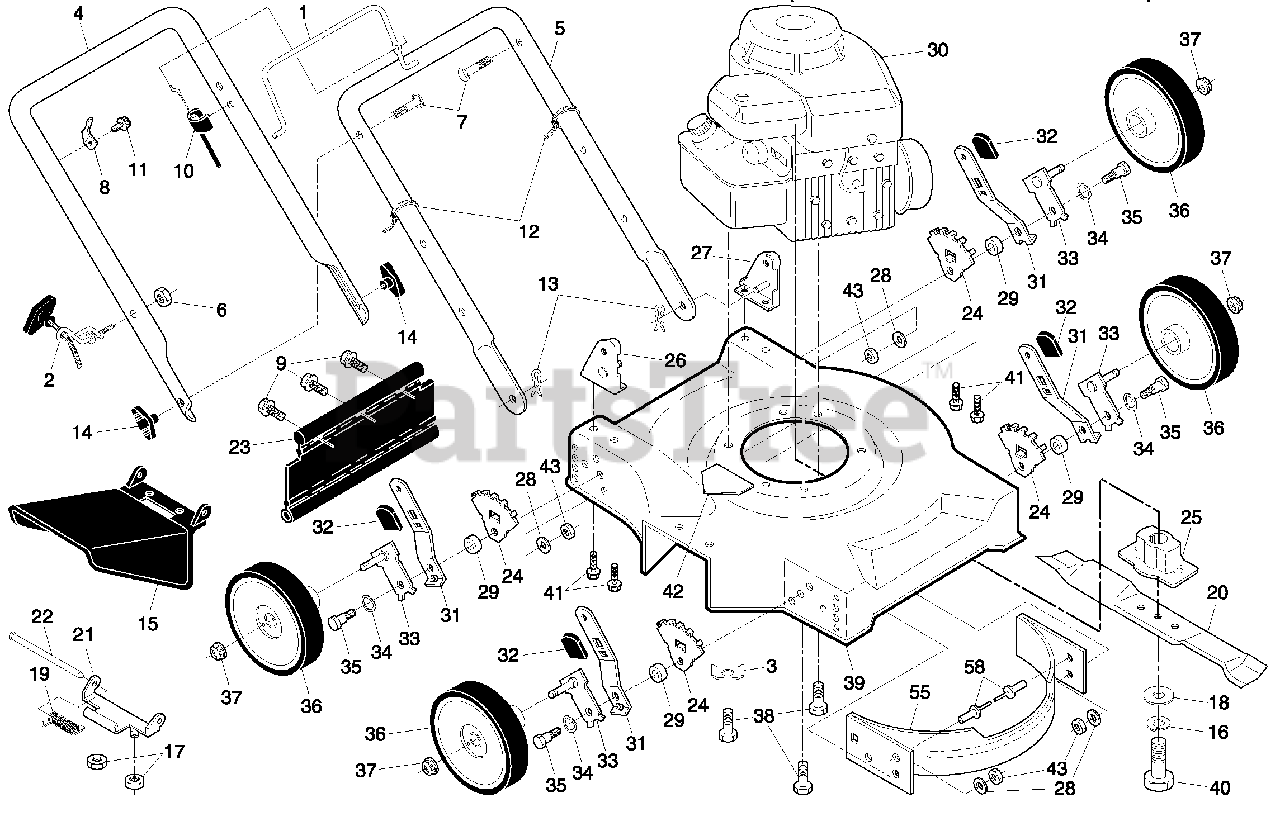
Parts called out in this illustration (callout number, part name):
1	Control Bar
2	Rope Guide
4	Upper Handle
5	Lower Handle
7	Handle Bolt 5/16-18 x 1-3/4
8	Up-Stop Bracket
9	Hex Washer Head Screw #10-24 x 1/2
10	Engine Zone Control Cable
11	Screw
12	Wire Tie
13	Hairpin Cotter
14	Knob, Handle
15	Discharge Guard
16	Helical Lock Washer 3/8
17	Locknut, Hex 1/4-20
18	Hardened Washer
19	Torsion Spring
20	Blade, 20"
21	Hinge Deflector
22	Hinge Rod
23	Rear Deflector
24	Wheel Adjusting Bracket
25	Blade Adapter
26	Handle Bracket Assembly, RH
27	Handle Bracket Assembly, LH
28	Washer, Flat
29	Spacer
31	Selector Spring
32	Selector Knob
33	Axle Arm Assembly
34	Belleville Washer
35	Shoulder Bolt
36	Wheel and Tire Assembly
37	Nut, Hex
38	Hex Head Thread Rolling Screw 3/8-16 x 1-1/8
39	Lawn Mower Housing
40	Hex Head Screw 3/8-24 x 1-3/8 Grade 8
41	Thread Cutting Screw 5/16-18 x 3/4
42	Danger Decal
43	Locknut, Hex 3/8-16
55	Baffl e, Front
58	Pop Rivet
58	Operator’s Manual, English
58	Operator's Manual, Spanish
58	Repair Parts Manual, English
